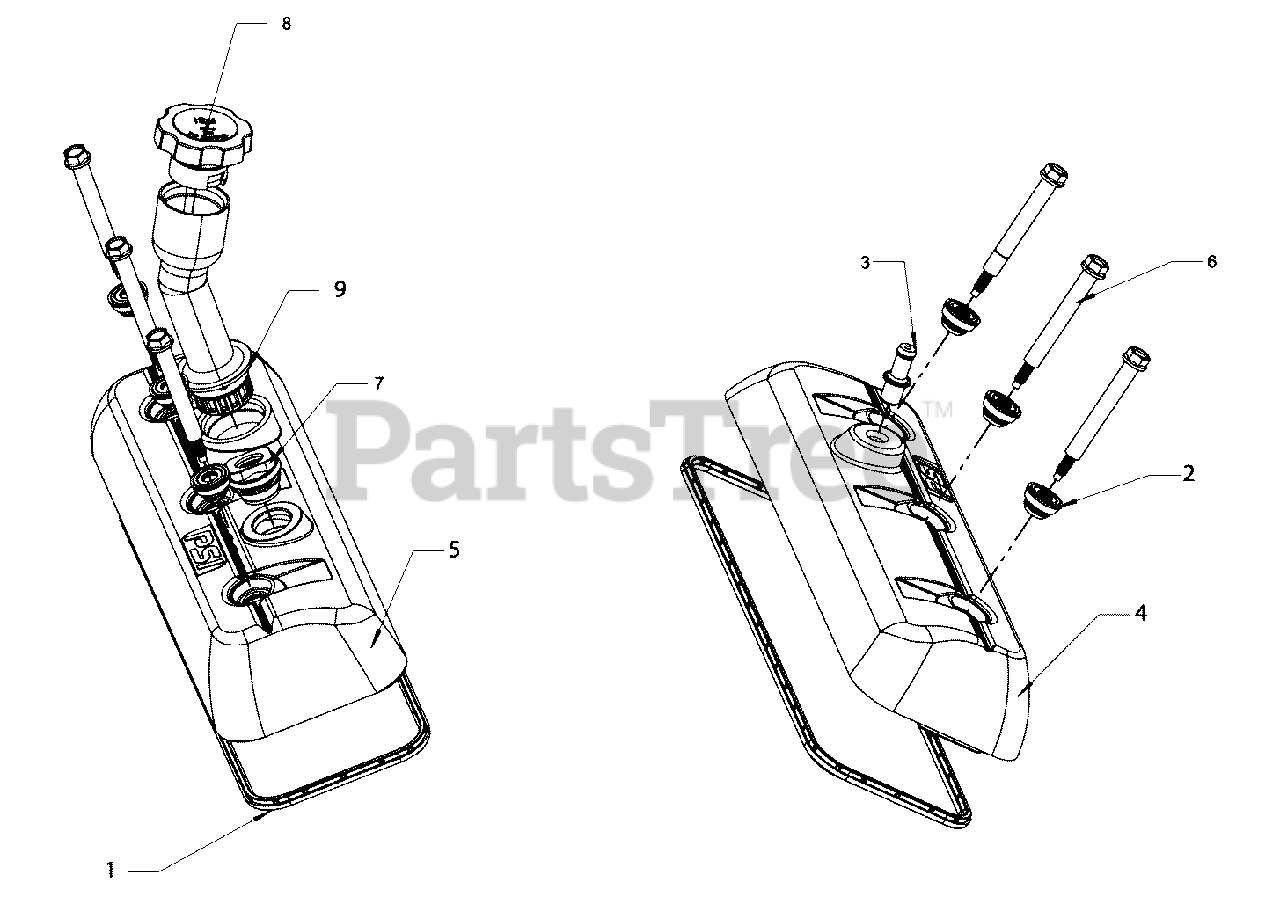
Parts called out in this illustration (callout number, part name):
1	GASKET, VALVE COVER
2	GROMMET
3	PCV
4	VALVE COVER
5	VALVE COVER - OIL FILL
6	BOLT, VALVE COVER
7	GROMMET
8	OIL CAP
9	PIPE
